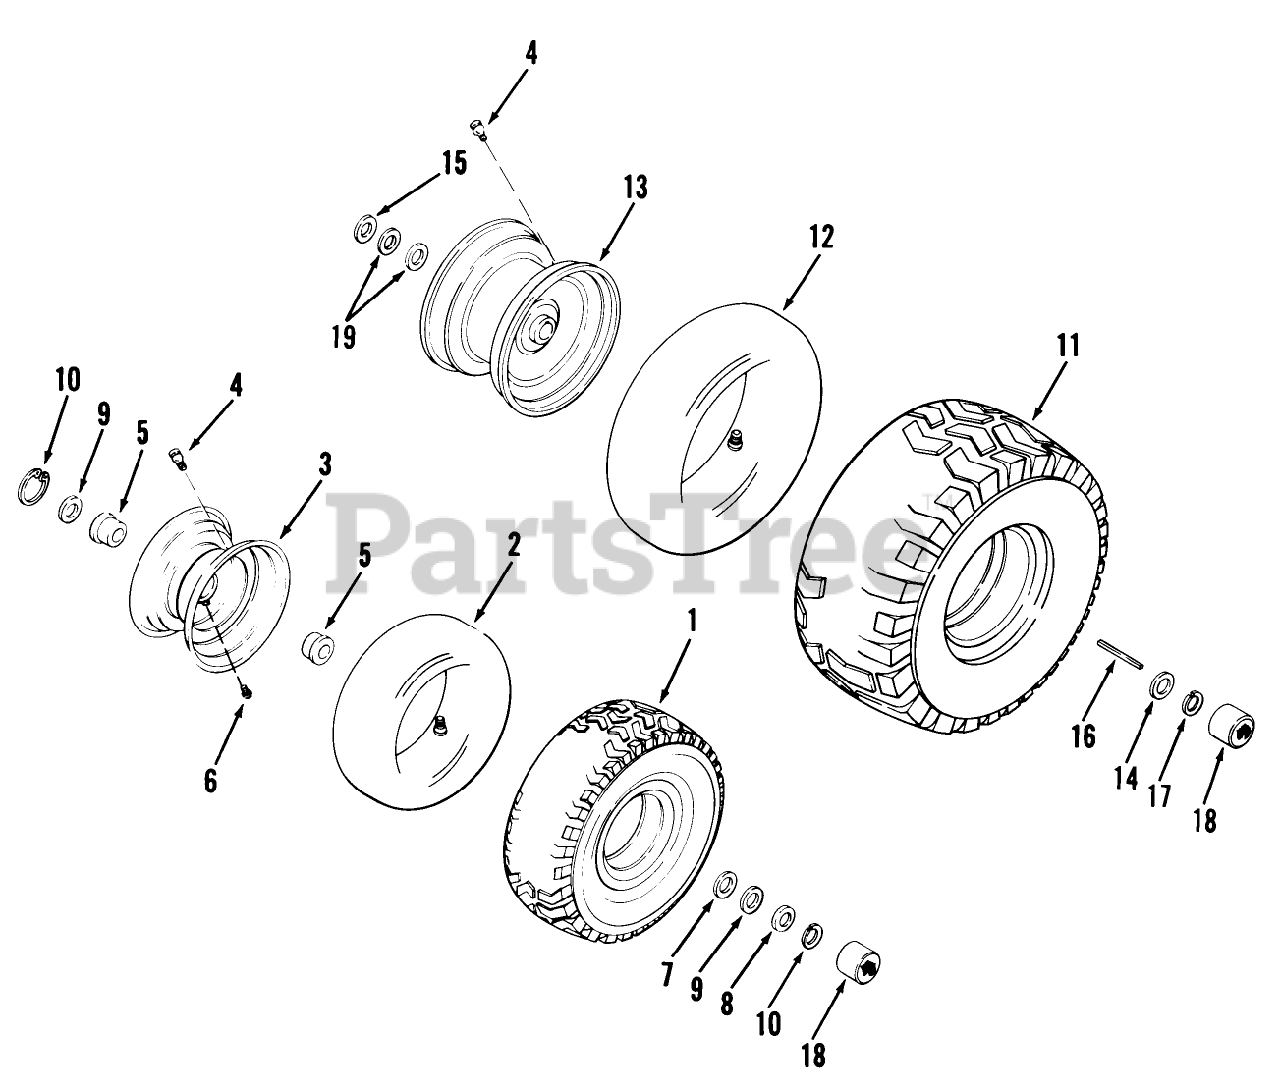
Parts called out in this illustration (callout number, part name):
1	TIRE
4	VALVE
5	BUSHING-FLANGED
7	WASHER-SHIM
8	WASHER
9	WASHER
13	Wheel-Rear
14	WASHER
15	WASHER
16	SQ KEY
19	WASHER
